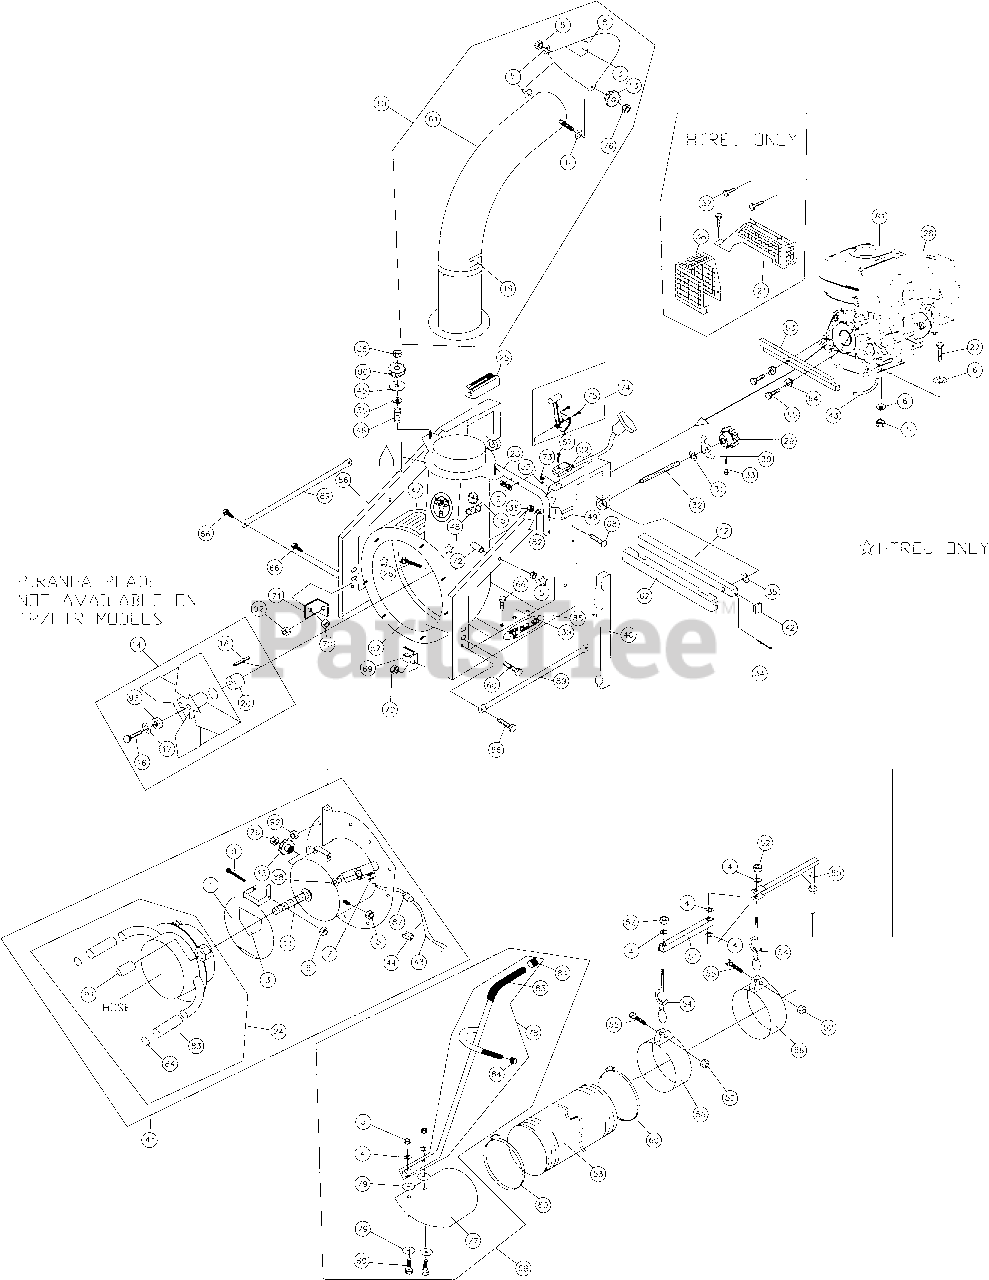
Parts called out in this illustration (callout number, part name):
1	FLAPPER 8" INTAKE W/ LABEL
2	PART NOT APPLICABLE ON THIS MODEL
3	LABEL DANGER KEEP HANDS AND FEET AWAY
4	WASHER 5/16 SAE (11/32 ID x 11/16 OD x 1/16)
5	NUT LOCK 5/16-18
6	WASHER 5/16 FLAT CUT (3/8 I.D. x 7/8 O.D. x 1/16)
7	PLUG 3/4"
8	DEFLECTOR EXHAUST 7"
9	CARRIAGE BOLT 5/16-18 x 3 1/2
10	ELBOW ASSY TR/HTR
11	CARRIAGE BOLT 3/4-10 X 6"
12	TUBE CLAMP
14	IMPELLER ASSY (SEE BLOCKED AREA)
15	LABEL READ OWNER'S MANUAL
16	SCREW CAP 3/8-24 x 2 3/4" GR 8 [33-38 Ft. Lbs. (45-52 N.m)]
17	WASHER LOCK 3/8 ST MED
18	KEY SQ. 1/4 x 2 3/4
19	LABEL DANGER FLYING MATERIAL
20	PART NOT APPLICABLE ON THIS MODEL
21	GUARD MANIFOLD
22	GUIDE STARTER ROPE (HALF)
23	TUBE REAR FRAME
24	COUPLER HOSE W/GRIP
25	PAD FRAME SHORT
26	CARRIAGE BOLT 5/16-18 x 2 1/4
27	SCREW CAP 5/16-18 x 1 1/2
28	ENGINE 18 H.P. VN W\CONTROL PANEL
29	KNOB PLASTIC 5/15 NUT INSERT
30	NUT LOCK W.A.
31	WASHER 3/4, PLASTIC
32	STUD 3/4 -10 x 5 1/2
33	SCREW MACHINE #10-24 x 2
34	PIN COTTER 1/8 x 1"
35	WASHER 3/8 SAE
36	NUT LOCK 3/8-16
37	SCREW SHEET METAL 1/4 AB x 3/4
38	GUARD MUFFLER
39	BASE ENGINE
40	PAD FRAME LONG
41	PLATE FRONT 8" TR W/INTERLOCK (SEE BLOCKED AREA)
42	PLUG CAP 1" SQUARE
43	CABLE ASSY SWITCH SV
44	CLIP-CABLE LIFT
45	WASHER-1.5 OD X 0.531 ID
46	SPRING COMPRESSION
47	LABEL CAUTION
48	LABEL EAR,EYE,BREATHING
49	LABEL WARNING ENGINE OVERHEAT
50	BOOM-PIVOT W.A.
51	TUBE-SQUARE BOOM ARM
52	NUT LOCK 1/4-20
53	HOSE 8" x 10' TR (COMES IN SEPERATE BOX)
54	CHAIN-LOOP ASSY
55	SCREW CAP 1/4-20 x 1 3/4
56	BAND HOSE BOOM 8" TR
57	HOUSING ASSY W/LABELS
58	NOZZLE ASSY 8" TR (SEE BLOCKED AREA)
60	CLAMP HOSE 8" TR
61	ELBOW EXHAUST WA
62	PAD FRAME CLAMP TUBE
63	SUPPORT PLATE ENGINE / SPACER ENG.
64	WASHER LOCK 3/8
65	SCREW CAP 3/8 - 16 X 1
66	FLANGE SCREW 3/8-16 X3/4
67	SCREW CAP 1/4-20 X 1 1/2
68	BOLT CARRIAGE 3/8-16 X 1 3/4" ZP
69	ANGLE BRKT R.H.
70	SER. HEX WASHER FLANGE NUT .375" - 16
71	ANGLE BRKT L.H.
73	WASHER FLAT CUT 1/4
74	PART NOT APPLICABLE ON THIS MODEL
75	SCREW MACHINE 10-24 x 1-1/2"
76	NUT LOCK 5/16-18 THIN HT.
77	NOZZLE FORMED STEEL 8"
78	HANDLE NOZZLE W / GRIP
79	WASHER FENDER 5/16
80	SCREW CAP 5 /16 - 18 X 1 3/4
81	LABEL DO NOT FILL WHEN ENGINE IS HOT
82	WASHER 3/8 FC
83	GRIP HANDLE
85	FRAME SIDE RIGHT WA TR/HTR
86	FRAME SIDE LEFT WA TR/HTR
87	STRAIN RELIEF
88	PLUNGER SWITCH
89	TUBE HANDLE LIFT
90	KNOB 3/8" SOLID HUB
92	NUT FLANGE 5/16-18 ZP
93	WASHER 1.5 OD X 0.453 X .25 THK
